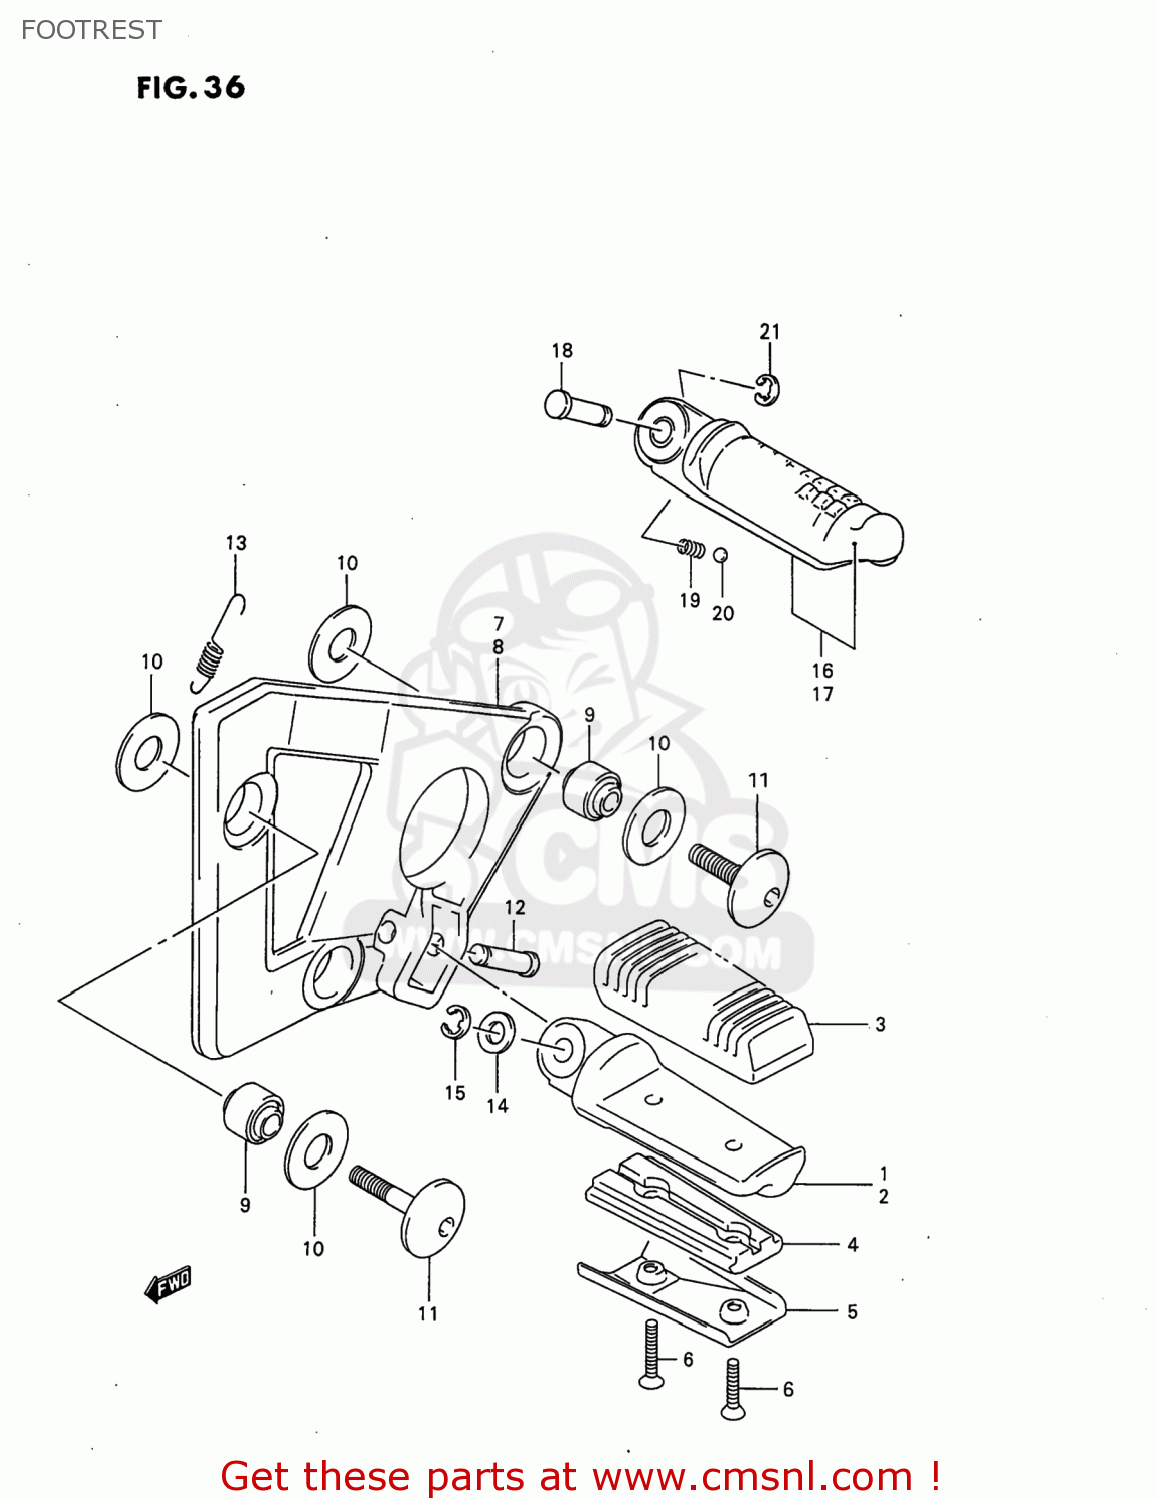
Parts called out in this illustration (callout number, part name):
1	BAR,FR FOOTREST,R
2	BAR,FR FOOTREST,L
3	RUBBER,FR FOOTREST
4	BAR,FRONT FOOTREST NO
5	COVER,FOOTREST BAR
6	SCREW
7	HOLDER,FRONT FOOTREST
8	HOLDER,FR FOOTREST
9	BUSH(12X20X16)
10	WASHER(12.6X24X1.9)
11	BOLT L:30
12	PIN(8X33.2)
13	SPRING
14	WASHER
15	E.RING
16	BAR,PILLION FOOTREST,RIGHT
17	BAR,PILLION FOOTREST,LEFT
18	PIN
19	SPRING
20	BALL
21	E.RING
